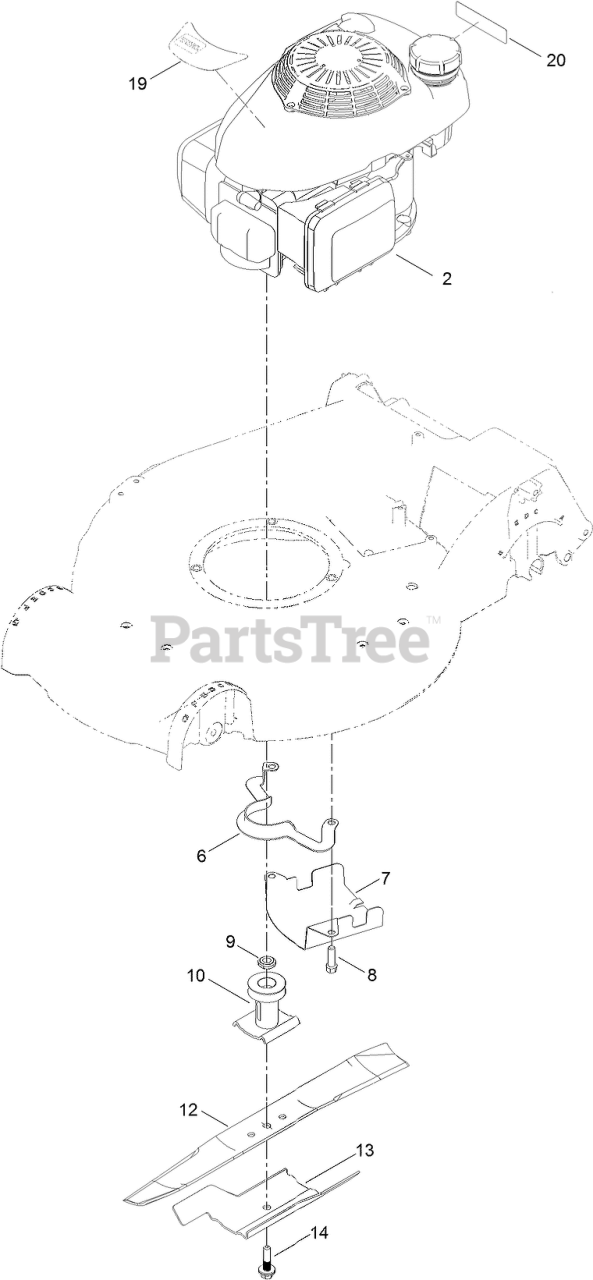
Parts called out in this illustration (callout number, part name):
6	GUIDE-BELT
7	SHIELD-GRASS
8	SCREW-TAPTITE
9	SPACER-DRIVER
10	DRIVER-BLADE
12	BLADE-21IN, RECYCLING
13	ACCELERATOR-BLADE
14	BOLT-BLADE
19	DECAL-SHROUD, HONDA
20	DECAL-ARRESTOR, SPARK
